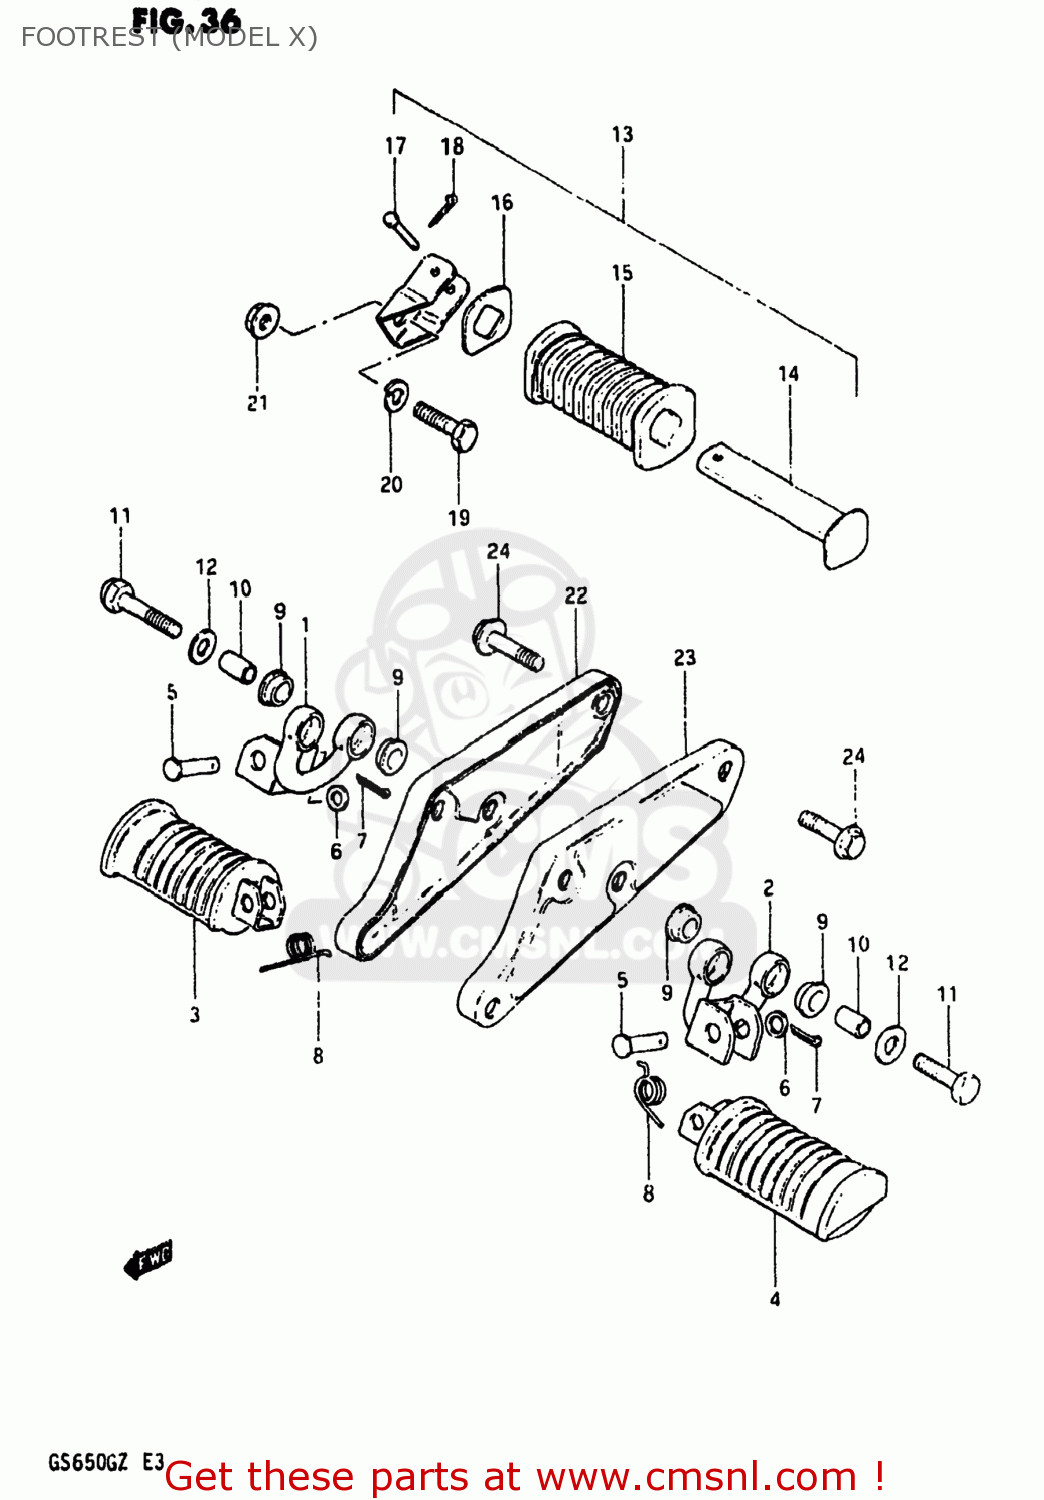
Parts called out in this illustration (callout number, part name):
1	BAR,FRONT FOOTREST
2	BAR,FRONT FOOTREST,LEFT
3	RUBBER,PILLION FOOTREST,R
4	RUBBER,PILLION FOOTREST,L
5	PIN
6	WASHER
7	PIN
8	SPRING
9	BUSH
10	SPACER (10.2X14X20)
11	BOLT
12	WASHER(10.5X28X2.3)
13	FOOTREST ASSY,PILLION,R
14	BAR,REAR FOOTREST,LEFT
15	RUBBER,PILLION FOOTREST
16	WASHER,FOOTREST RUBBER
17	PIN
18	PIN
19	BOLT,M10X1.25X
20	LOCK WASHER
21	NUT
22	BRACKET
23	BRACKET
24	BOLT
